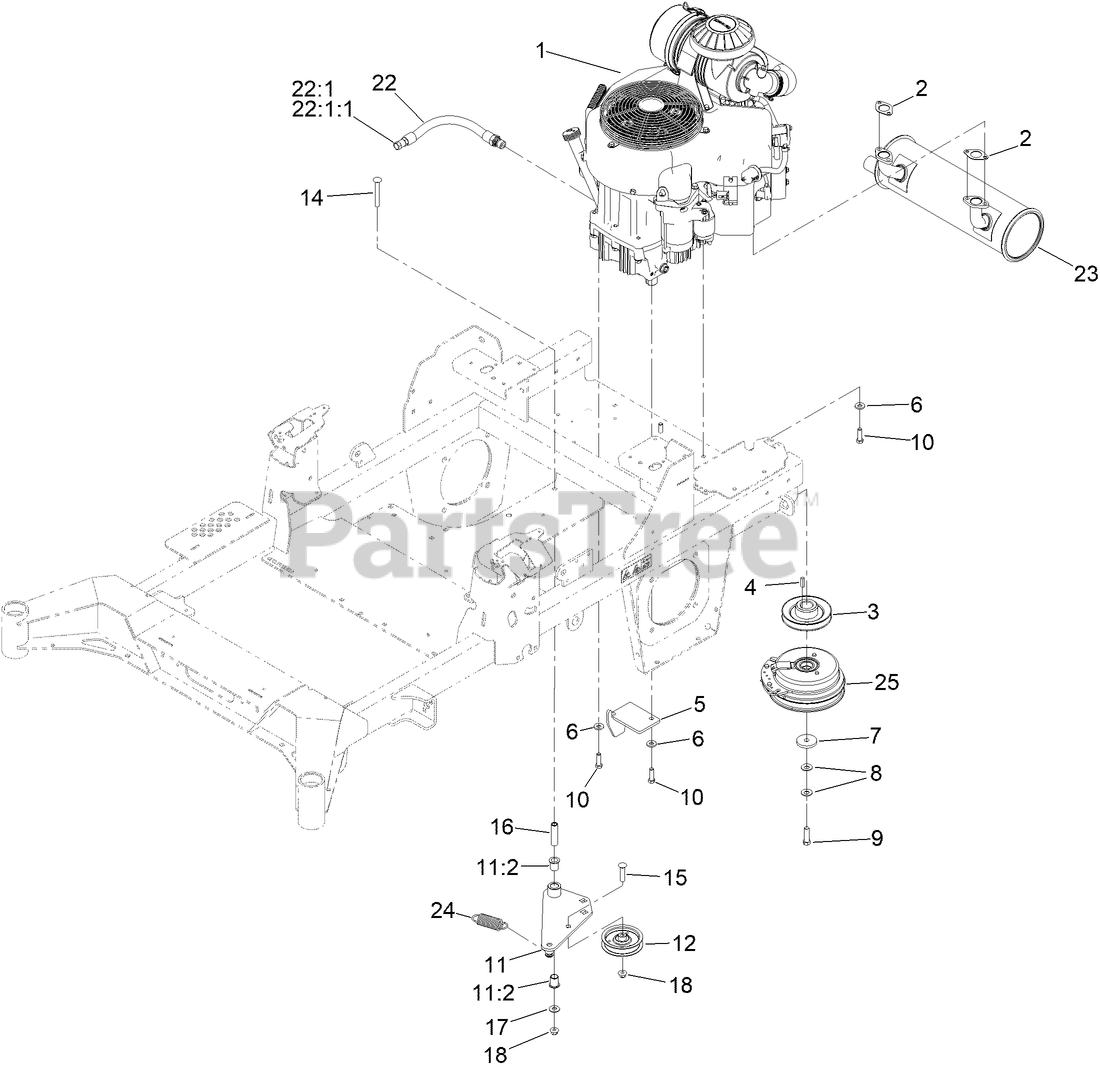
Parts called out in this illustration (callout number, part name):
2	GASKET-EXHAUST
3	SHEAVE, W/HUB
5	ANCHOR-CLUTCH
6	WASHER-BELLEVILLE
7	WASHER-CLUTCH
8	WASHER-SPRING
9	SCREW-HH, W/LOCTITE
10	SCREW-HH
11	IDLER ARM ASM
11:2	BUSHING-FLANGE
12	PULLEY-IDLER, FLAT
14	SCREW-CARR
15	SCREW-CARR
16	BUSHING, IDLER PIVOT
17	WASHER-FLAT
18	NUT-HF, NI
22	ENGINE OIL DRAIN HOSE ASM
22:1	PLUG-HH
22:1:1	O-RING
23	MUFFLER
24	SPRING-IDLER
